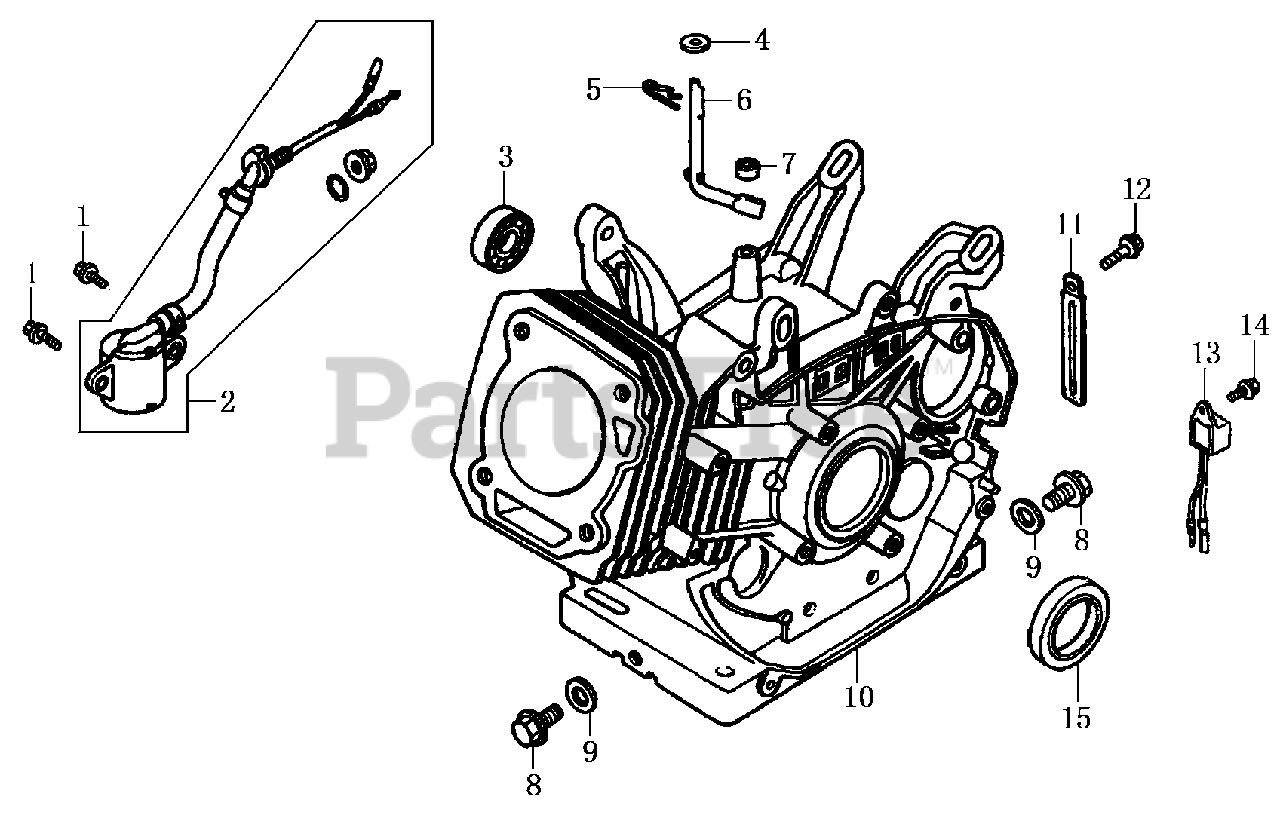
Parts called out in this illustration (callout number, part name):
1	BOLT, FLANGE
2	SWITCH ASSY., OIL LEVEL
3	BEARING, RADIAL BALL 6202
4	WASHER, 8x16x1.2
5	PIN, LOCK, 10MM
6	SHAFT, GOVERNOR ARM
7	SEAL, OIL
8	BOLT, DRAIN PLUG
9	WASHER, DRAIN PLUG, 12MM
10	CRANKCASE
11	CABLE CLEAT
12	BOLT, FLANGE, 6×12
13	ALERT UNIT, OIL
14	BOLT, FLANGE, 6×12
15	SEAL, OIL
